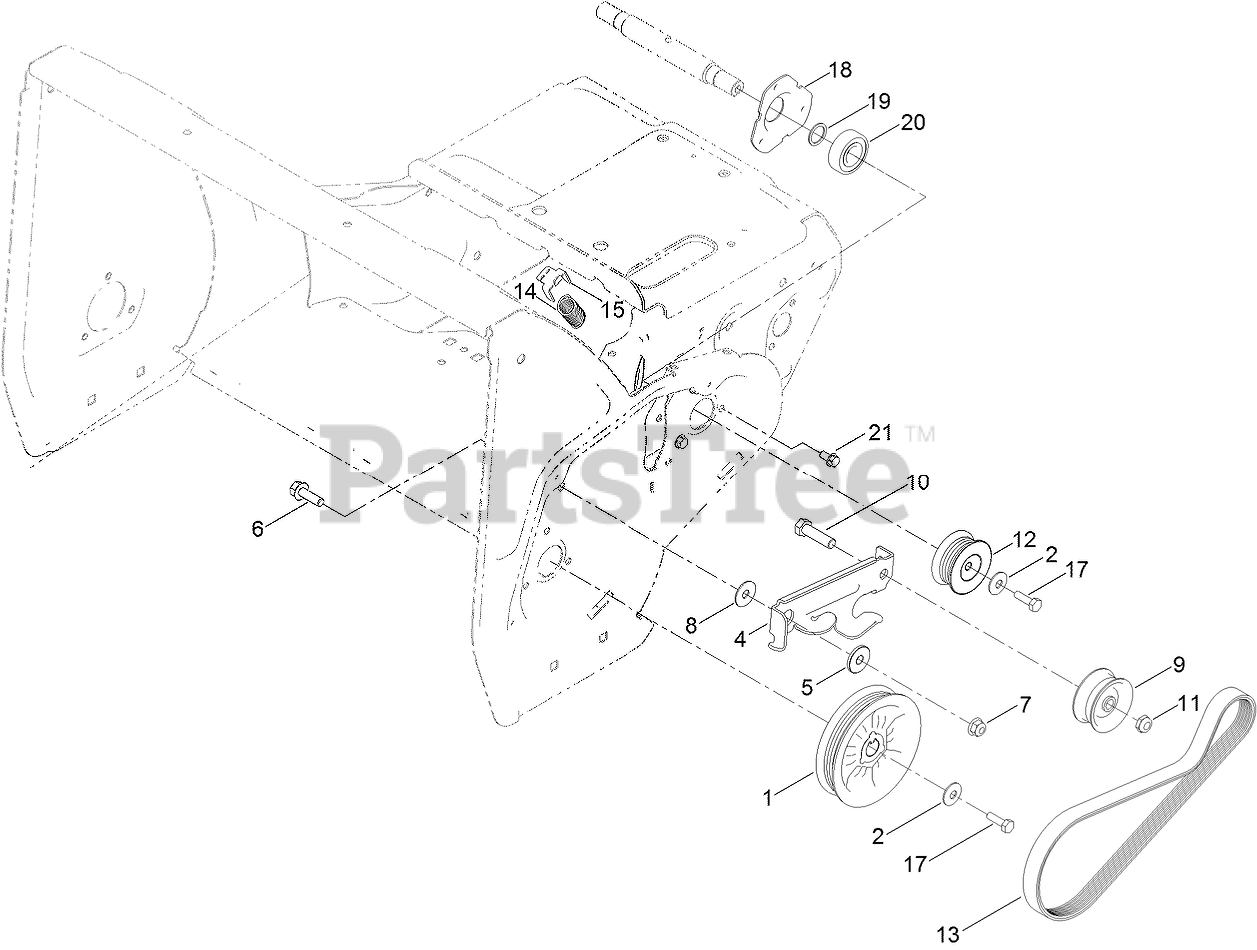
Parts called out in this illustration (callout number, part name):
1	PULLEY-ROTOR
2	WASHER-BELLEVILLE
4	ARM-ENGAGEMENT, ROTOR
5	BUSHING-IDLER
6	SCREW-HHF
7	NUT-HF
8	WASHER
9	PULLEY-IDLER, FLAT
10	SCREW-HH
11	NUT-HEX
12	PULLEY-JACKSHAFT, ROTOR
13	BELT-POLY V
14	SPRING-EXTENSION
15	CLIP-SPRING
17	SCREW-HH
18	FLANGE-BEARING
19	WASHER-THRUST
20	BEARING-BALL
21	SCREW-HWH
